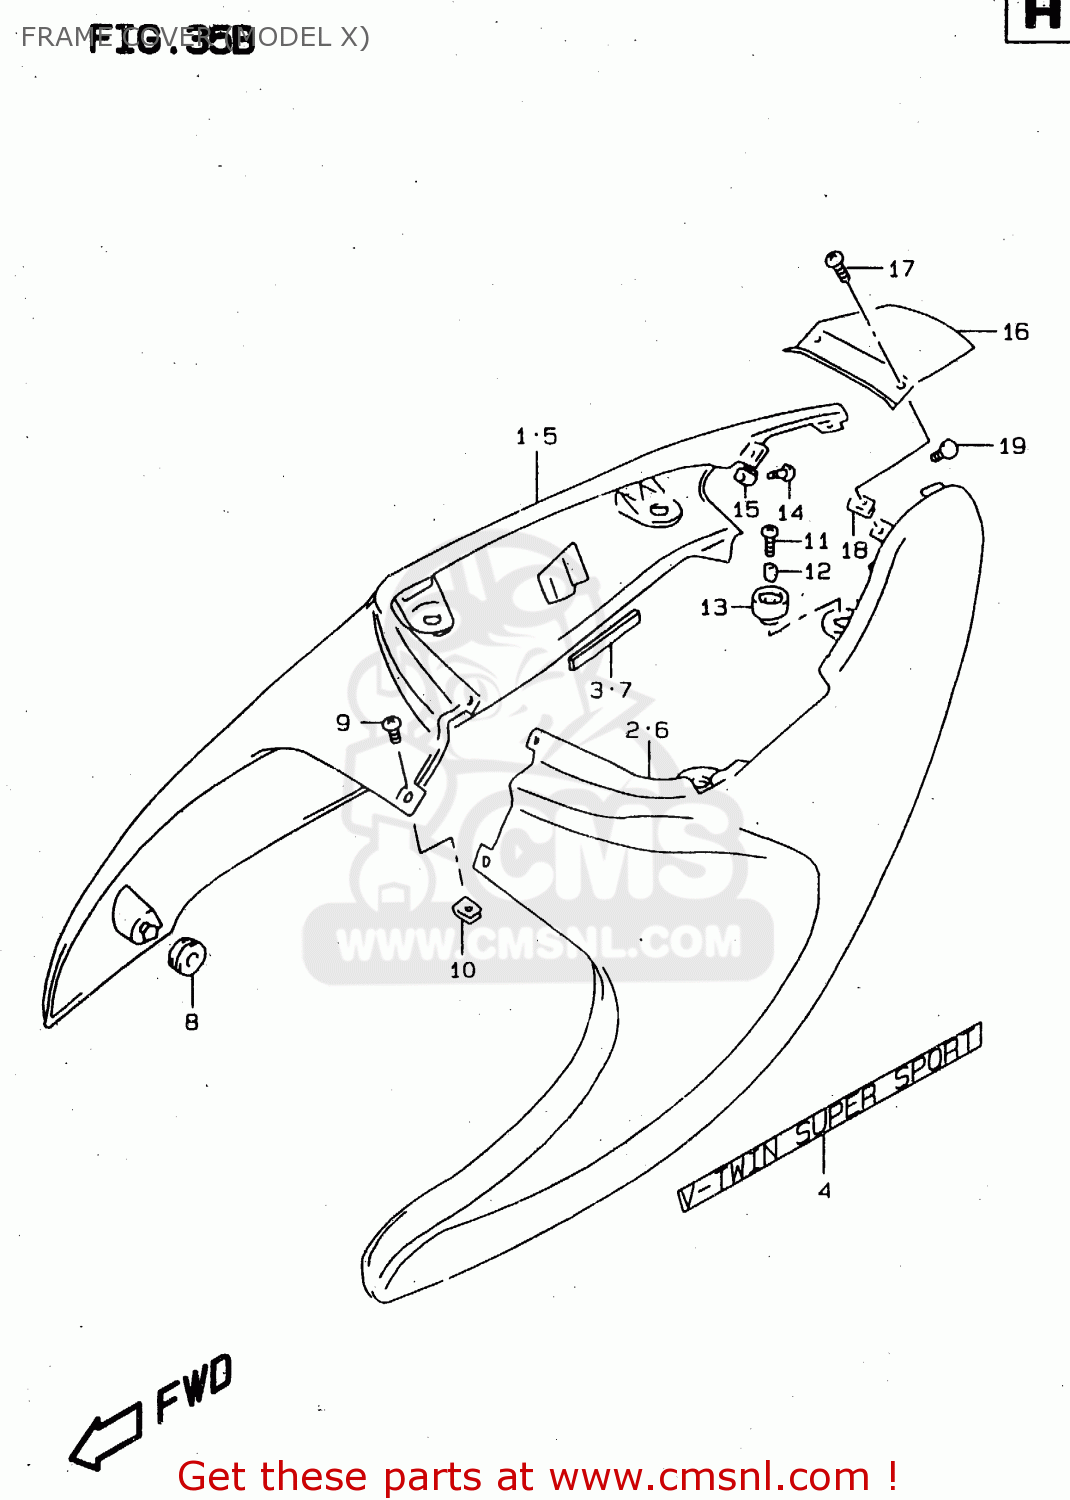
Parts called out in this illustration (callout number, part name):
1	COVER,FRAME,R(BLUE)
2	COVER,FRAME,L(BLUE)
3	CUSHION,FRAME COVER
4	EMBLEM
5	COVER,FRAME,R(BLACK)
6	COVER,FRAME,L(BLUE)
7	CUSHION,FRAME COVER
8	CUSHION
9	SCREW
10	NUT
11	SCREW(6X20)
12	SPACER(6.5X10X9.4)
13	CUSHION
14	SCREW(5X16)
15	NUT
16	COVER,FRAME CTR
17	SCREW
18	NUT
19	CUSHION
